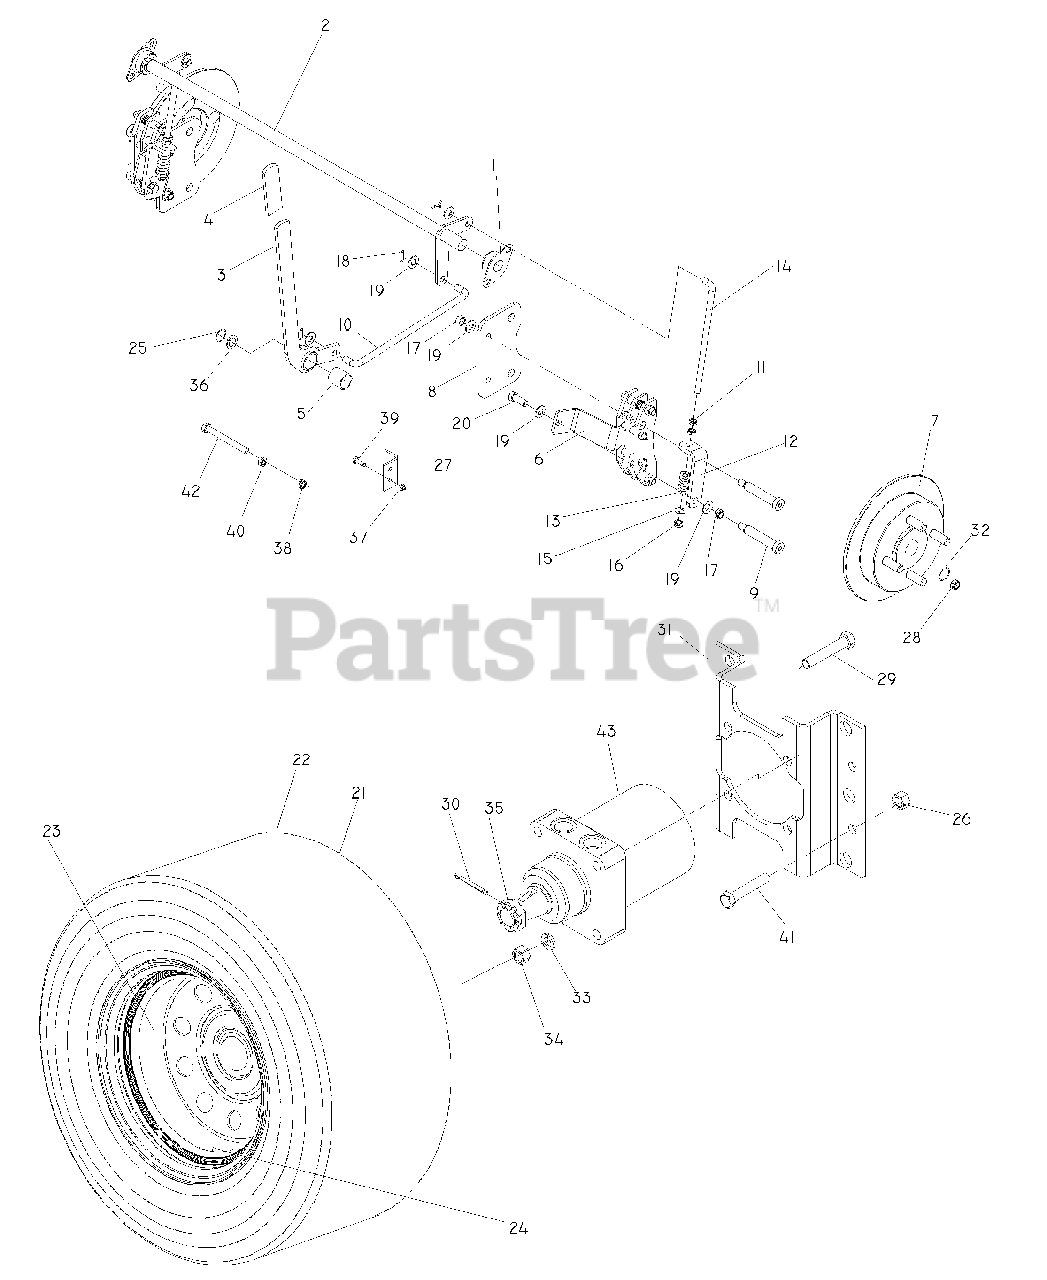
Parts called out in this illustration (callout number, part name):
1	FLANGE BEARING
2	BRAKE CROSS SHAFT
3	LEVER, BRAKE WELDMENT
4	GRIP BRAKE HANDLE
5	BUSHING
6	CALIPER ASSEMBLY
8	PLATE, BRAKE
9	SB 3/8-16 X 2-1-1/2 SKT HDD ZD
10	LINKAGE, BRAKE
11	NUT 3/8-24 JAM
12	BRACKET, L
14	LINKAGE, REAR BRAKE
15	WASHER 3/8 SAE FLAT
16	NUT 3/8F CENTERLOCK
17	NUT HEX 3/8-16 NYLON, THIN
18	COTTER PIN 3/32 X 3/4
19	WASHER 3/8 SAE FLAT
20	HCS 3/8C X 1
21	RP.WHEEL.ASM.23X10.5-12.TURFMA
21	TIRE WHEEL ASM 23 X 9.5-12
22	TIRE.TURF.MASTER.23X10.5-12
22	TIRE.TURF.MASTER.23X9.5-12
23	RIM 2.5" NEG OFFSET 8.5" WIDE
23	RIM, 12 X 7, 1" NEG OFFSET
24	VALVE STEM TR-412
25	RETAINING RING, 7/8"
26	NUT 1/2-13 HEX NYLOC ZD
27	BRACKET
28	LUG NUT 1/2F
29	HCS 1/2C X 2 3/4
30	PIN COTTER 4MM X 45MM
31	MOTOR STANDOFF
32	MACHINE BUSHING
33	WASHER 1/2" SPLIT LOCK
34	NUT HEX 1/2
35	NUT 3/4-16 HEX SLTD GR5 ZD
36	BSHG .875 X 1.375 X .074 ZD
37	NUT 1/4-20 NYLOC
38	NUT 3/8-16 NYLOC
39	HCS 1/4C X 3/4 HCS
40	NUT 3/8C WHIZ
41	HCS 1/2C X 1 1/4 SERRATED HEAD
42	HCS 3/8C X 2 1/2
43	WHEEL MOTOR, TJ
